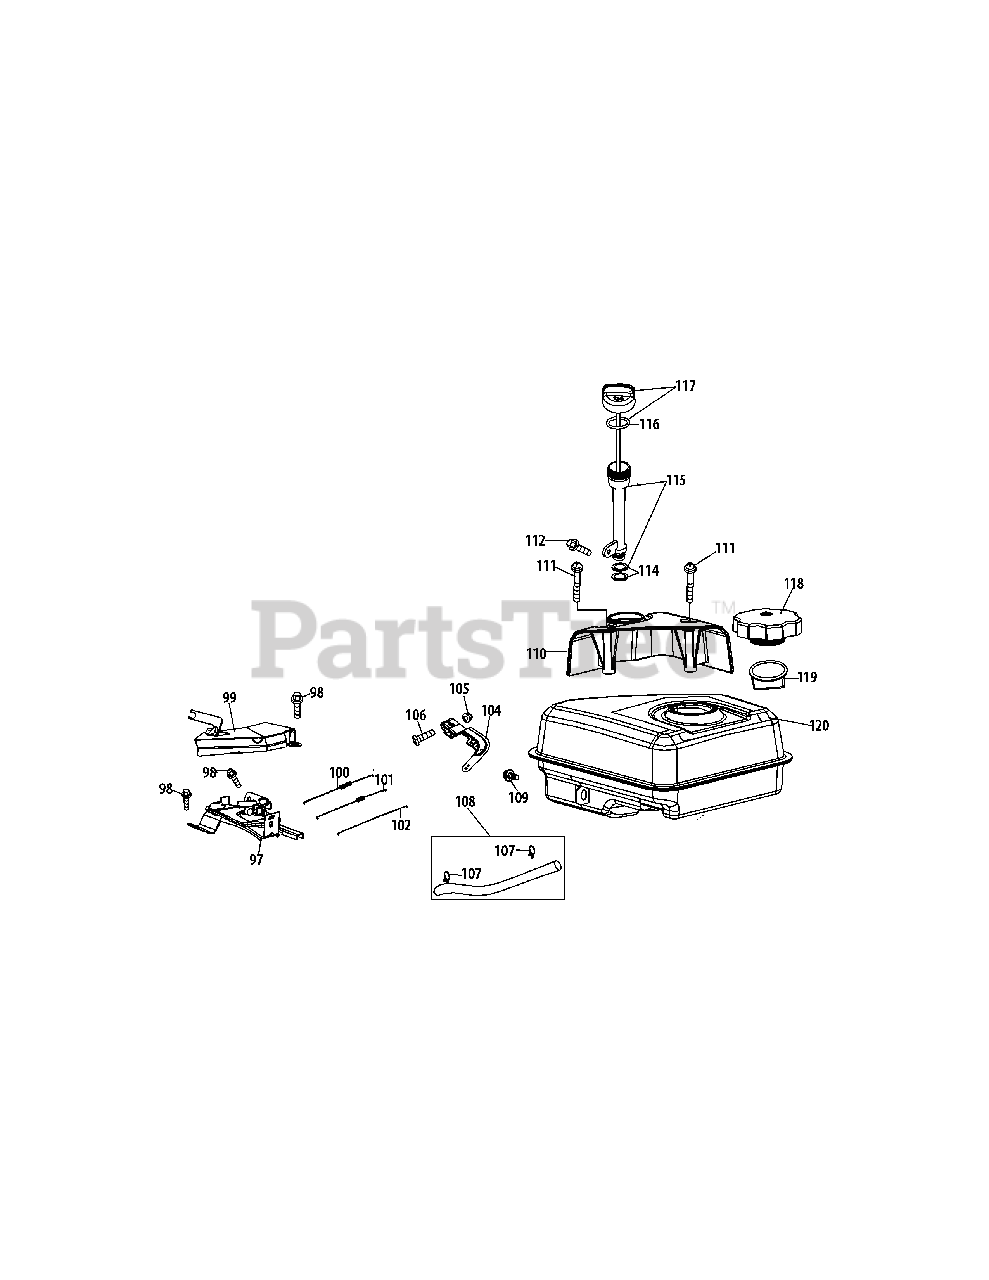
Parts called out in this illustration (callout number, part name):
97	Primer Bracket
98	Bolt M6×12
99	Governor System Shield
100	Governor Spring
101	Throttle Linkage Spring
102	Throttle Linkage
104	Governor Arm
105	Nut M6
106	Governor Arm Bolt
107	Fuel Hose Clamp
108	Fuel Line Kit
109	Bolt M6×12
110	Dipstick Decoration Cover
112	Bolt M6×12
114	Oil Fill Tube O-Ring
115	Oil Fill Tube Assembly
116	Dipstick O-Ring
117	Dipstick Assembly
118	Fuel Cap Assembly
119	Fuel Level Indicator
120	Fuel Tank Assembly
